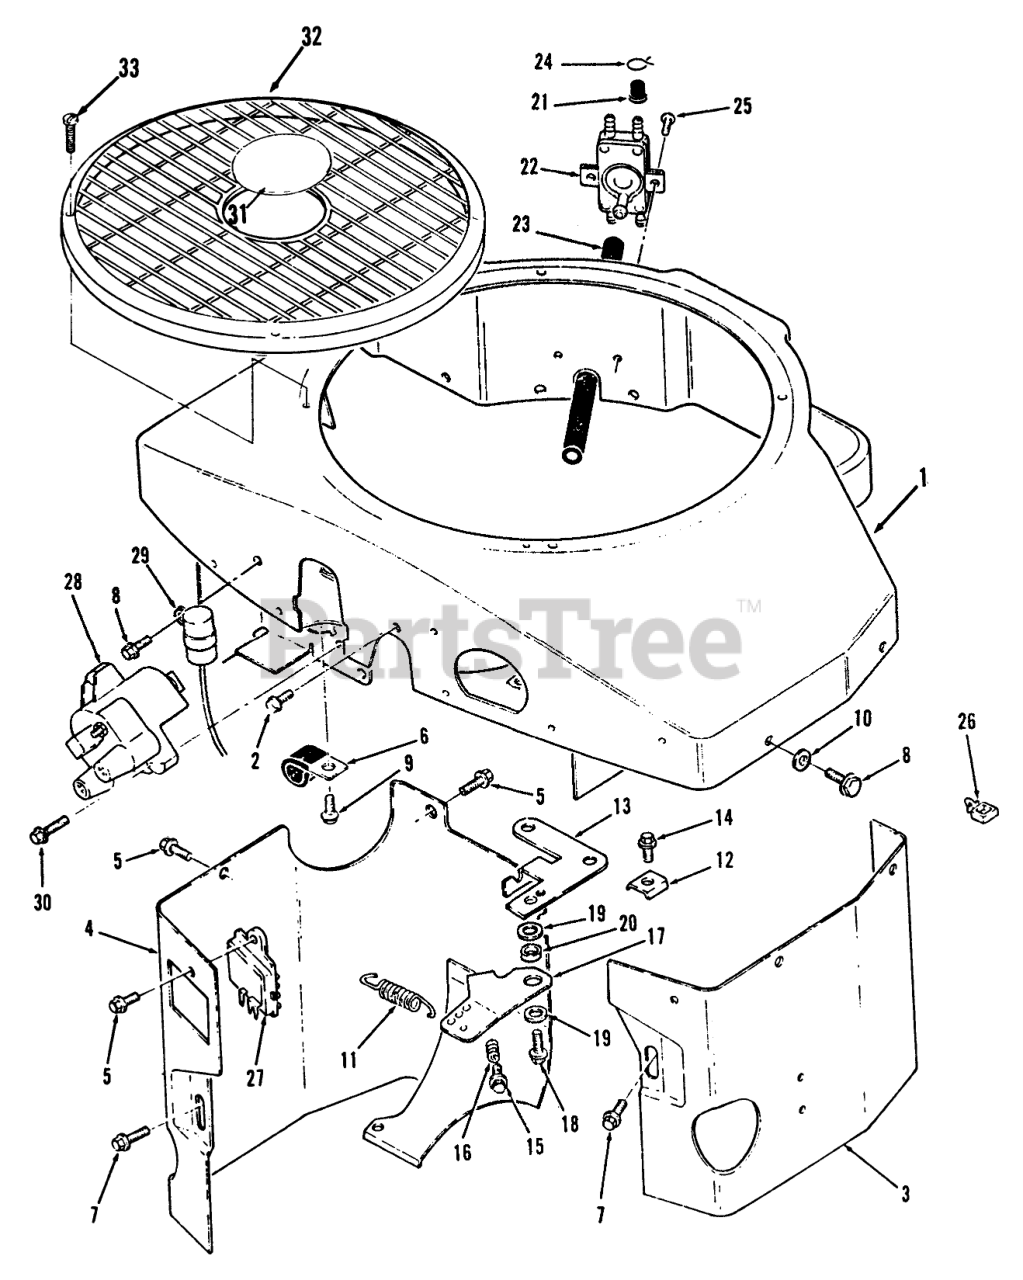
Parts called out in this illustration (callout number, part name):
1	HOUSING
2	Bolt
3	Cylinder Air Housing
4	CYLINDER AIR HSG L H
5	Bolt
6	Clip
7	Bolt
8	Bolt
9	Bolt
10	Washer
11	Spring
12	Clamp
13	Bracket
14	Bolt
15	Bolt
16	Spring
17	Arm
18	Bolt
19	Screw
20	Bushing
21	Cap
22	FUEL-PUMP
23	Hose
24	Clamp
25	Screw
26	Clip
27	Regulator
28	Coil-Ignition
29	Condenser
30	Bolt
31	Plug
32	Guard
33	Screw
